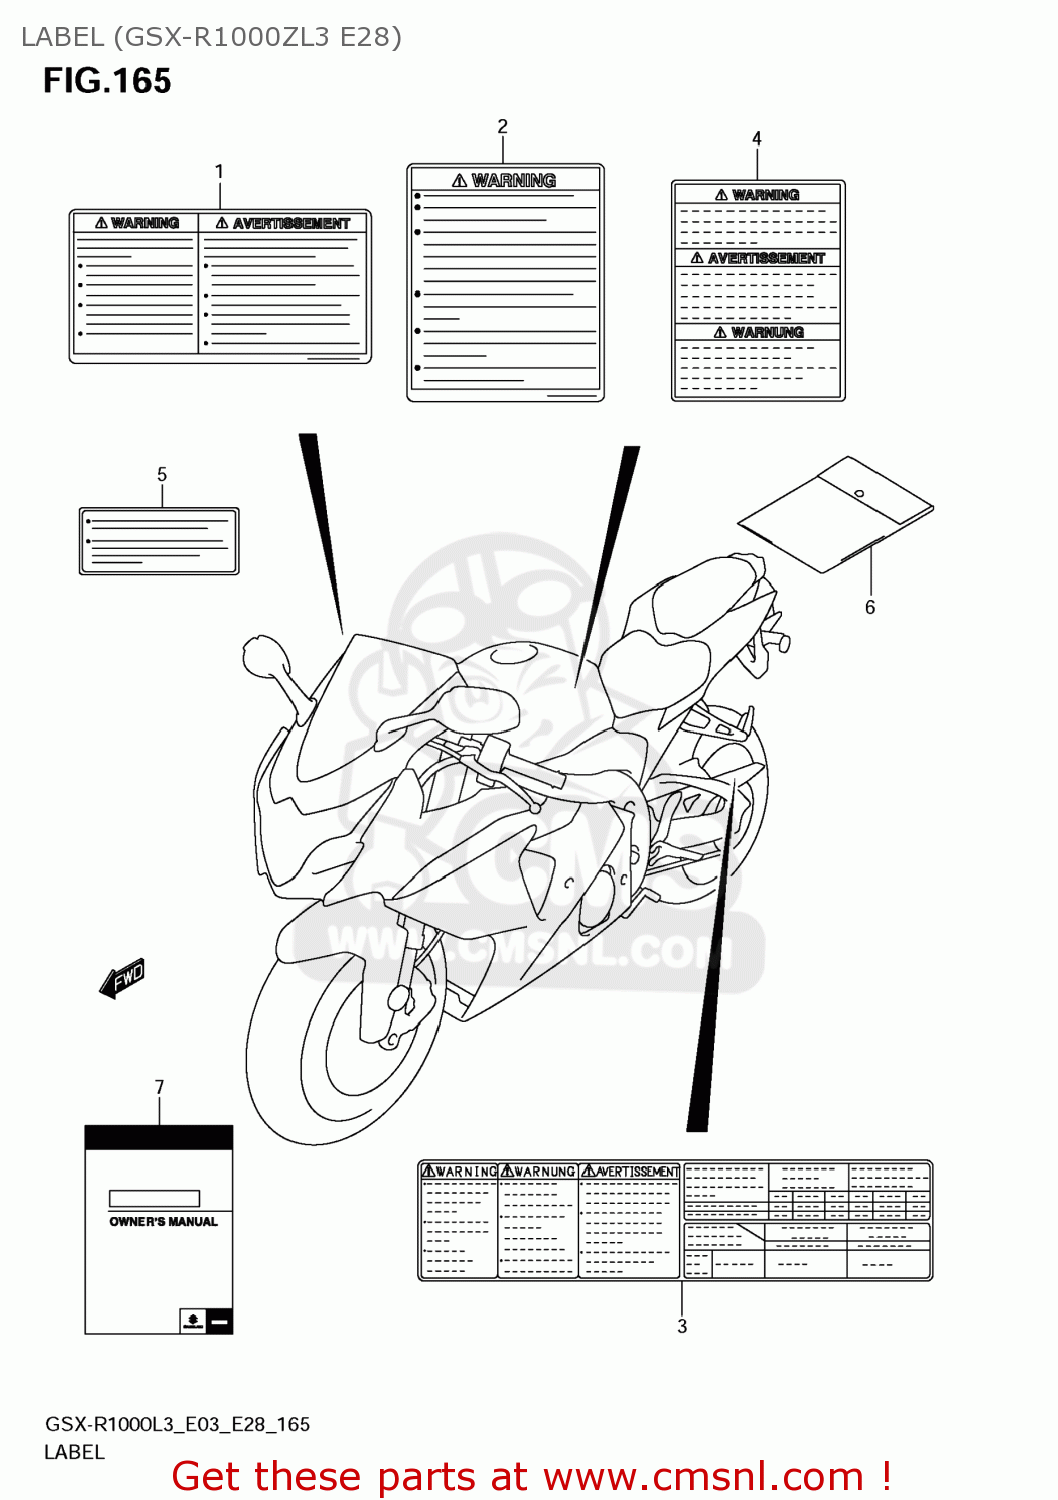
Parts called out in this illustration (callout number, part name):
1	LABEL,GENERAL WARNING
2	LABEL,SCREEN
3	LABEL,TIRE INFORMATION
4	LABEL,WARNING STEERING
5	LABEL,FUEL INFORMATION
6	BAG,OWNER'S MANUAL
7	MANUAL,OWNER'S
